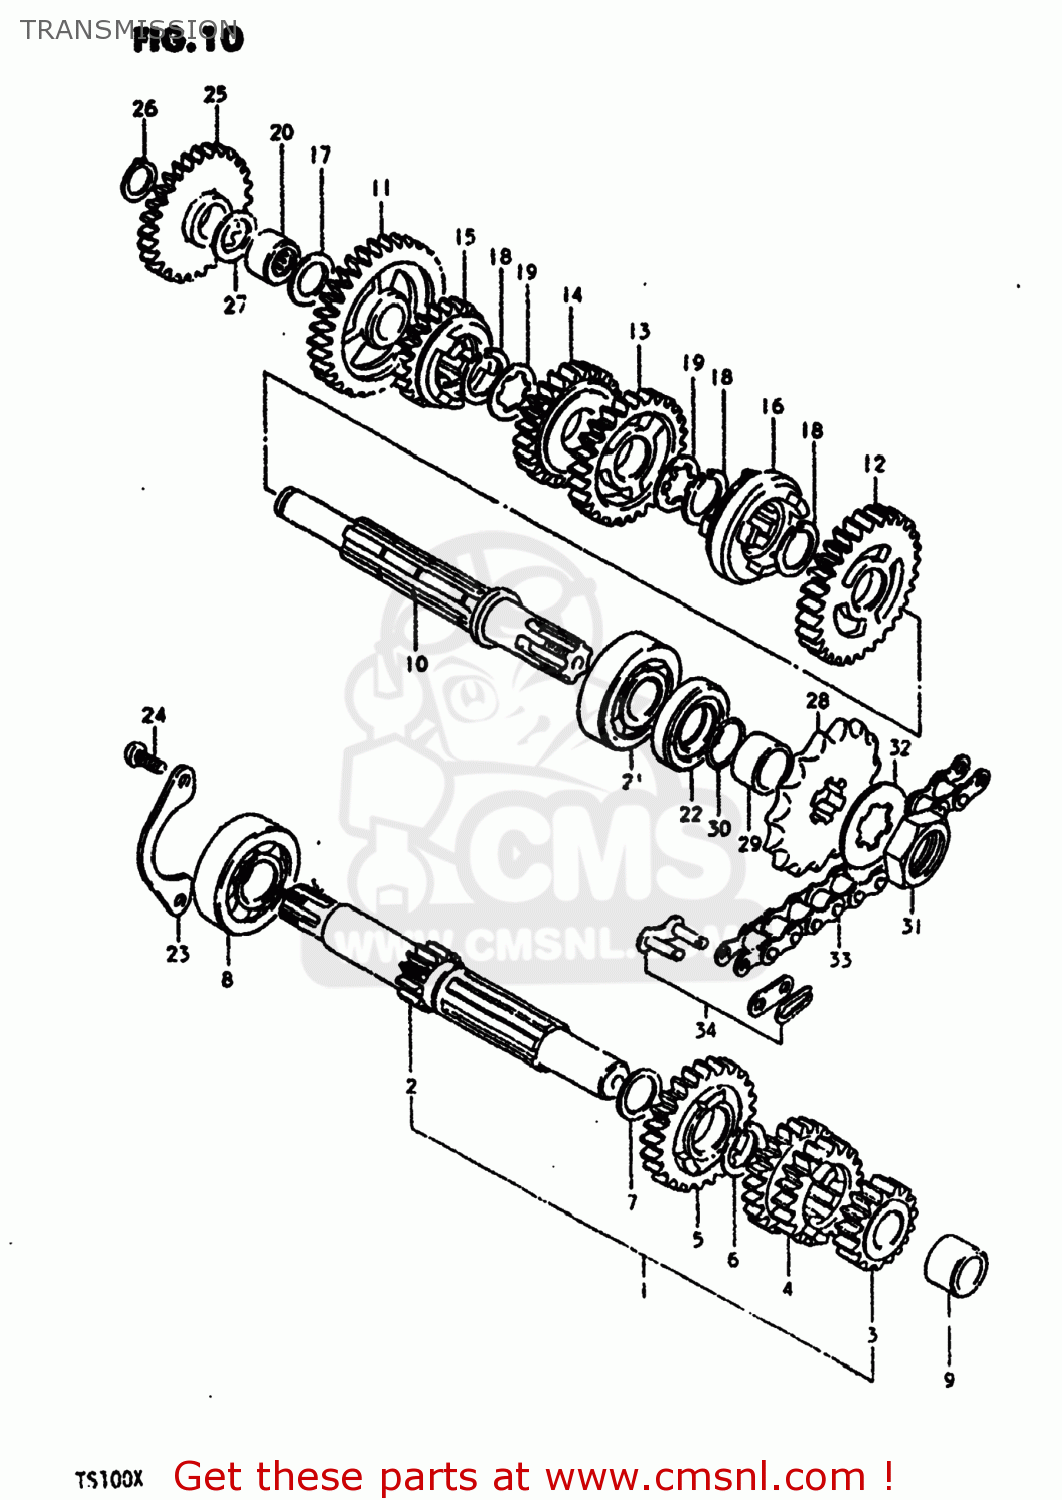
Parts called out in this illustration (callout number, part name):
1	SHAFT ASSEMBLY,COUNTER
2	SHAFT,COUNTER
3	GEAR,SECOND DRIVE
4	GEAR,THIRD/FOURTH DRIVE
5	GEAR,FIFTH DRIVE
6	CIRCLIP
7	WASHER
8	Bearing
9	BUSH(15X22X15)
10	SHAFT,GEAR SHIFT
11	GEAR,1ST DRIVEN
12	GEAR,SECOND DRIVEN
13	GEAR,THIRD DRIVEN
14	GEAR,FOURTH DRIVEN
15	GEAR,FIFTH DRIVEN
16	WHEEL,SECOND DRIVEN GEAR
17	WASHER,THRUST
18	CIRCLIP
19	WASHER,LOCK
20	BEARING(15X22X12)
21	Bearing
22	SEAL,OIL(25X40X7)
23	RETAINER,CNTR SHAFT BEARING
24	SCREW 6X12
25	GEAR,KICK STARTER IDLE
26	CIRCLIP,15MM
27	WASHER,THRUST
28	SPROCKET,ENGINE
29	SPACER(20X25X12.5)
30	O RING(D:1,ID:19.5)
31	NUT
32	WASHER,LOCK
33	CHAIN ASSEMBLY,DRIVE
34	JOINT ASSEMBLY,CHAIN
